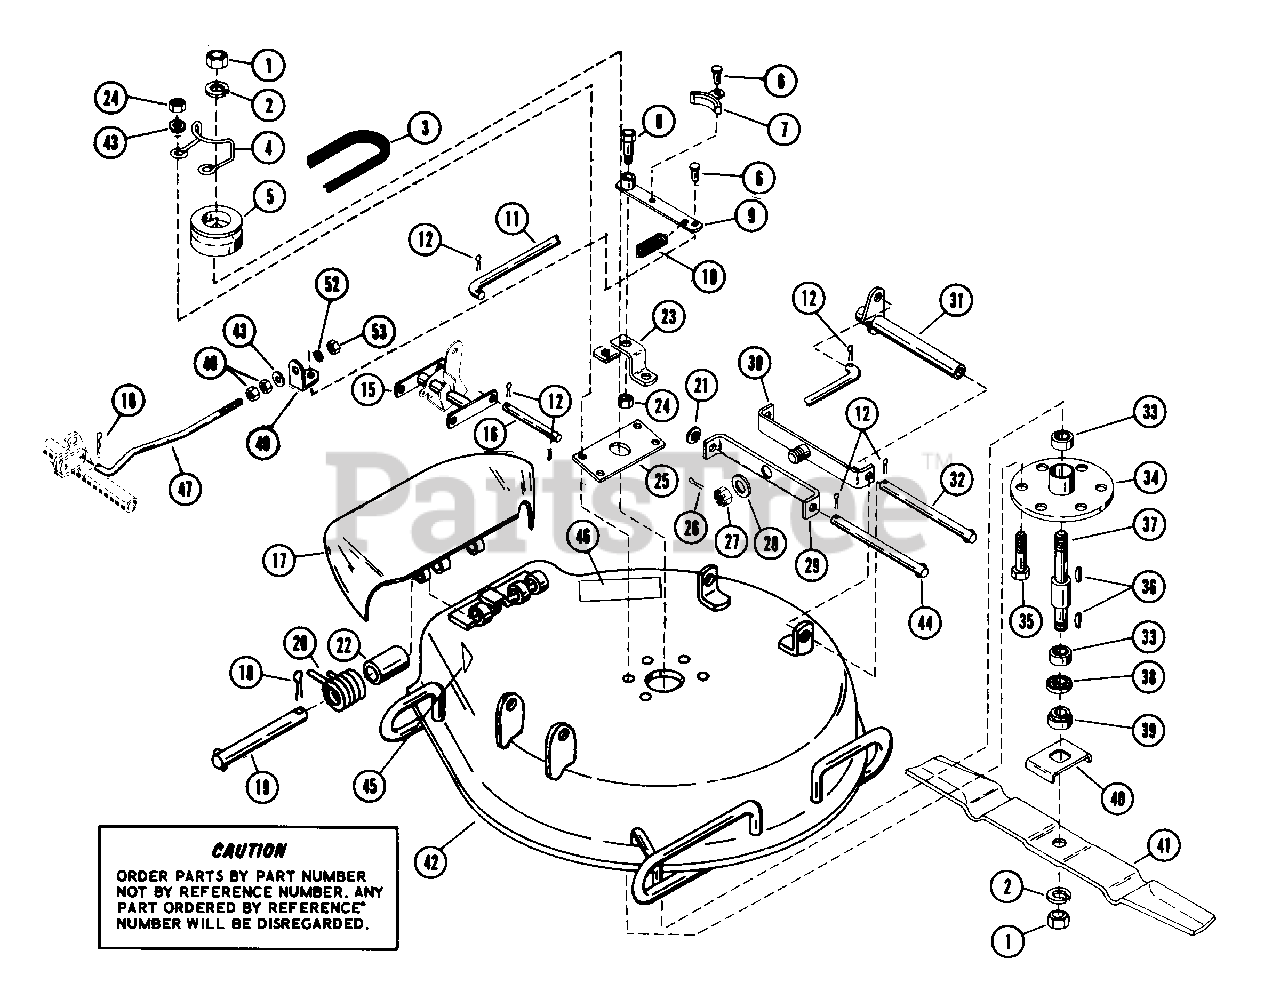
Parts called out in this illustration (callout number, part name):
1	NUT-JAM .75-10 PL
2	WSHR-LK .750X.188 MED PL
3	V-BELT, 5L-RAW EDGE
4	MOWER BELT FINGER
5	MOWER SHEAVE
6	RVT .25X.50 RH ST
7	BLADE BRAKE
8	SHOULDER BOLT .50 X 1.75
9	BLADE BRAKE ARM
10	SG-TENS .072X.51X5.31 WLD 25
11	HEIGHT LINK ROD
12	PIN-COTR .12X1.0 PL
15	PAN HEIGHT BRACKET
16	ADAPTER PIN
17	PAN CHUTE EXTENSION
18	PIN-COTR .09X.75 PL
19	CLEVIS PIN
20	SG-TORS .095X.50X 1.0
21	WSHR-FL-STL .531X1.062X.095 PL
22	BSHG-SLV .334 X .502 X 1.437
23	BLADE BRAKE SUPPORT
24	NUT-LK-CTR .375-16 GR A PL
26	PIN-COTR .12 X 1.25 PL
27	NUT-JAM-SL .625-18
28	WSHR-FL-STL .630X1.005X.062 PL
31	REAR RAISING BRACKET
32	REAR BRACKET PIN
33	BRG-BALL .751X1.78X.61
34	SPINDLE HOUSING
35	BLT-HEX .38-16X1.00 PL
36	KEY-WDRF .188X.75X.313 SAE 9
37	MOWER SPINDLE
38	BEARING SLINGER
39	RETAINER HUB
40	BLADE TRAY
41	BLADE, MOWER
42	MOWER PAN ASSEMBLY
43	WSHR-FL-STL .38X.875X.083 PL
44	HANGER PIN
45	SAFETY LABEL
46	MOWER CAUTION LABEL
47	BLADE BRAKE ROD
48	NUT-HEX .312-18
49	BRAKE ROD GUIDE
52	GROMMET
53	NUT-LK .312-18 GR A PL
